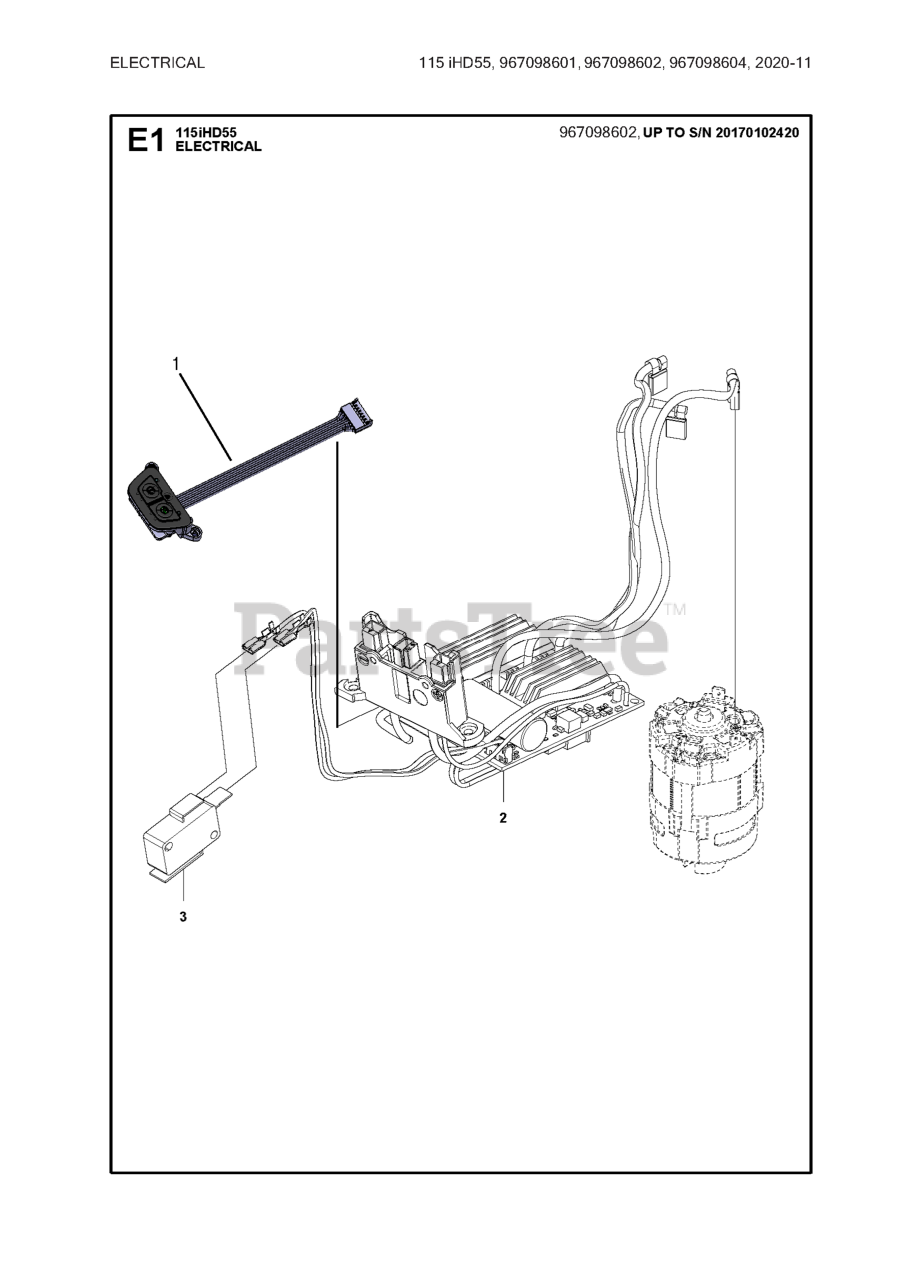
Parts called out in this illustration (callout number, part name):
1	KEYPAD ASSEMBLY
2	CONTROL UNIT CONTROL UNIT BLDC
3	MICRO SWITCH
